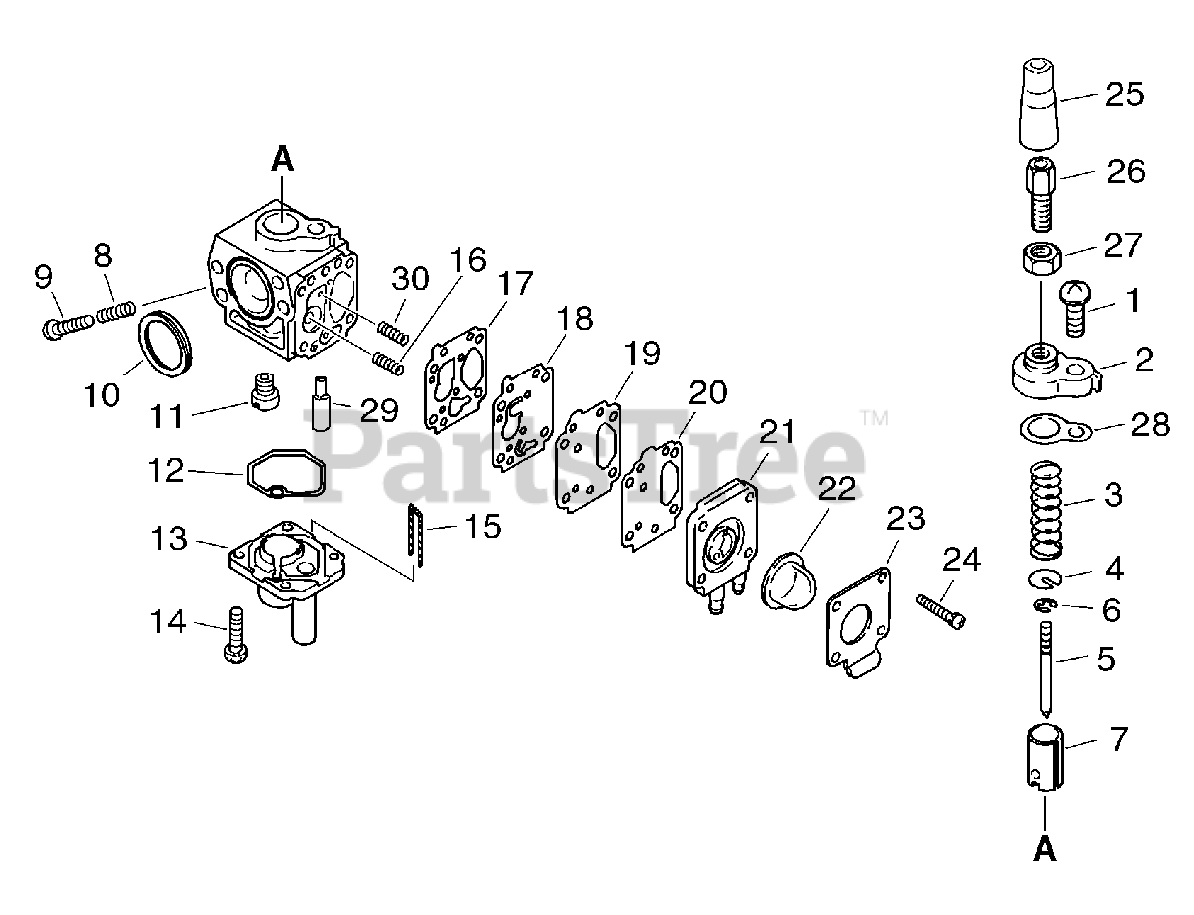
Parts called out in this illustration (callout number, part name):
2	Cover, Top
3	Spring, Throttle
4	Seat, Spring
5	Needle, Jet
7	Valve, Throttle
8	Spring, Idle Adjust
10	Gasket, Frange
11	Jet, Main
12	Gasket, Chamber
13	Chamber, Float
14	Screw 3x10
15	Wire, Drain
16	Spring, Adjustment
18	Diaphragm, Fuel Pump
19	Plate,Pump
20	Gasket, Fuel Pump
21	Cover, Pump
22	Pump, Priming
23	Plate, Pump
25	Cap, Rubber
26	Adjust,Cable
28	Jet, Needle
30	Spring,Back Up
